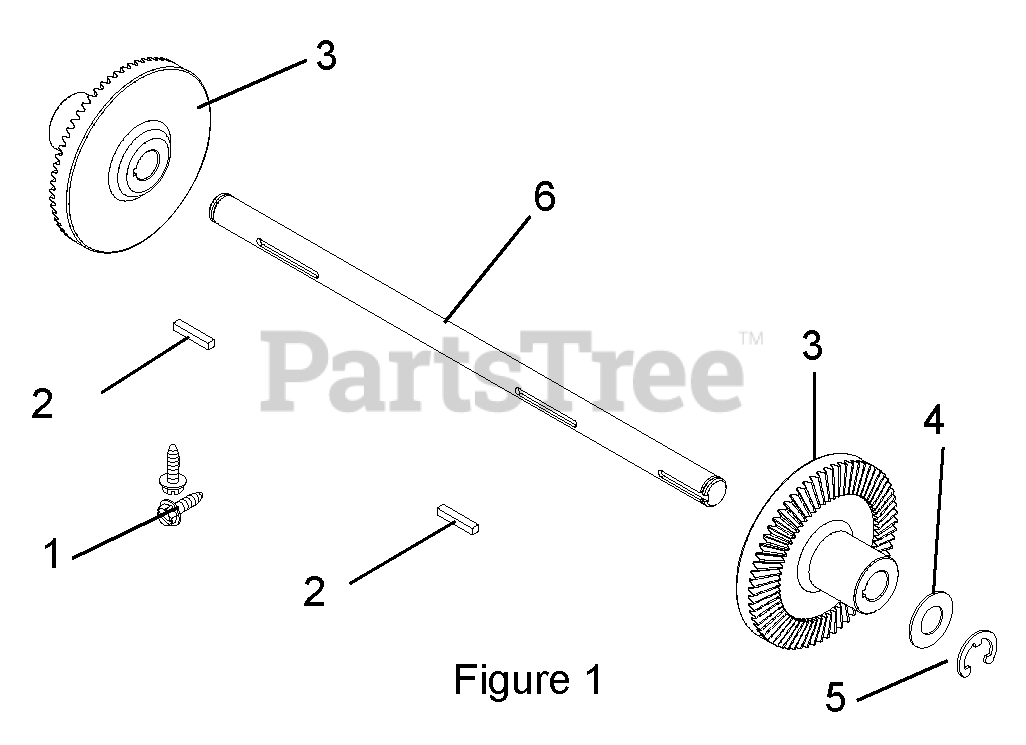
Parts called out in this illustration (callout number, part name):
1	SCR-TAP 10-24X.375 PRE-COAT 80
2	KEY, 1/8 X 1/8 X 1.0
3	GEAR, BEVEL (CU INFL, KEYWAY)
4	WASHER, .500X.750X.020 THRUST
5	RG-RTNG-EXT .500X.042 (E)
6	SHAFT-TRANS OUTPUT
